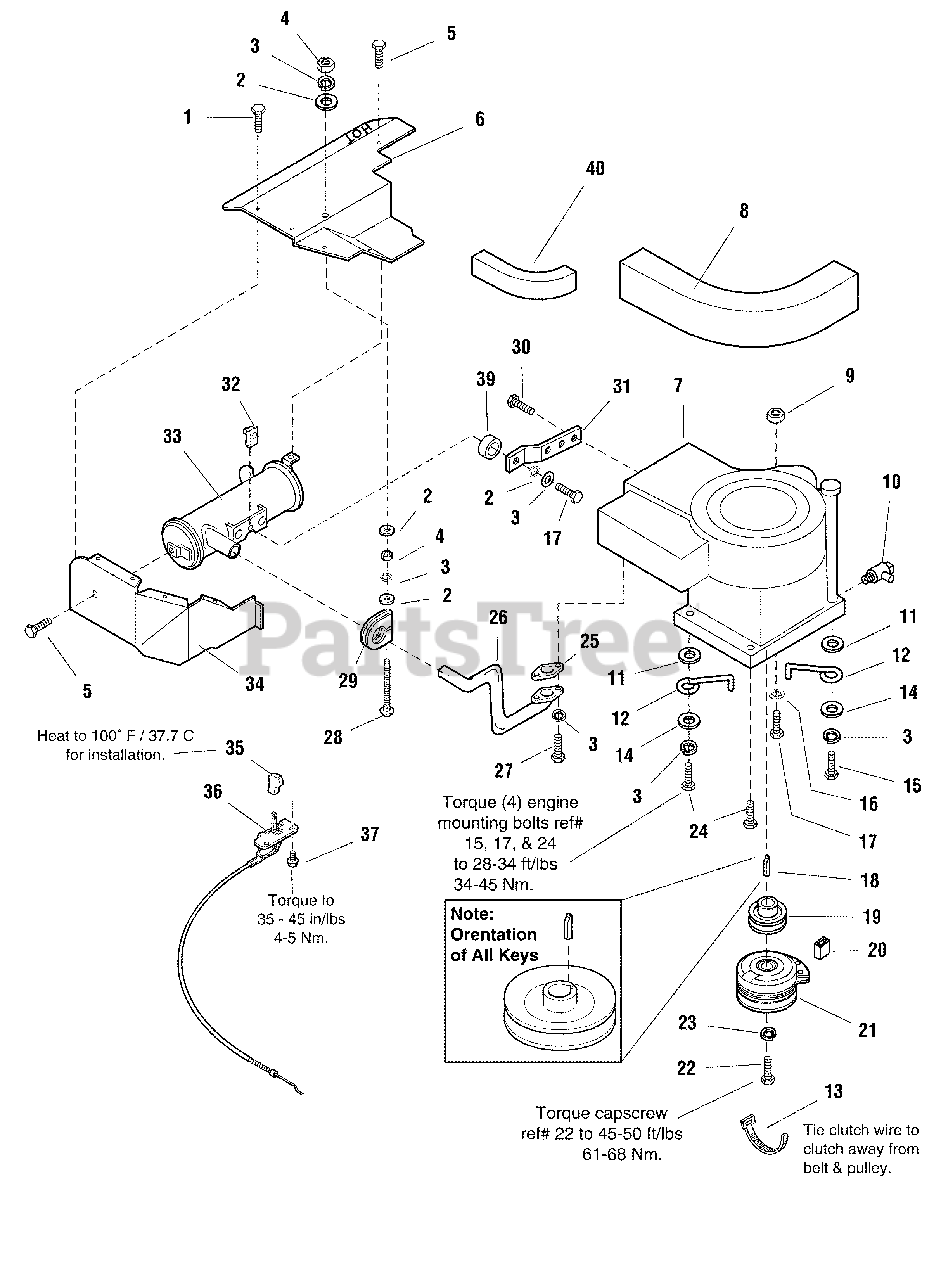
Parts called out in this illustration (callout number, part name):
1	CAPSCREW, Self-Tapping, #10-16 x 1/2
2	WASHER, 5/16
3	LOCKWASHER, 5/16
4	NUT, Hex, 5/16-18
5	CAPSCREW, Hex Head, Taptite, 5/16-18 x 1/2
6	DUCT, R.H., Top
8	SEAL, Air Inlet
9	NUT, Flange, Whizlock, 5/16-18
10	VALVE, Shut-Off
11	WASHER, Plain
13	TIE, Self Locking
14	WASHER, 3/8
15	CAPSCREW, Taptite, 3/8-16 x 2
16	PUSH NUT, 5/16-18
17	CAPSCREW, Hex, Whizlock, Flange, 5/16-18 x 1-1/2
18	KEY, Hi-Pro
19	PULLEY, Engine
20	SLEEVE, Clutch Anchor
21	CLUTCH, Electric, Kit
22	CAPSCREW, Hex Head, 7/16-20 x 2-1/2
23	LOCKWASHER, 7/16
24	CAPSCREW, Taptite, 3/8-16 x 1-1/2
25	GASKET, Muffler
26	PIPE, Exhaust
27	CAPSCREW, Socket Head, 5/16-18 x 3/4
28	CARRIAGE BOLT, 5/16-18 x 3-1/4
29	CLAMP, Muffler
30	CAPSCREW, Hex Head, 1/4-20 x 7/8
31	SUPPORT, Muffler
32	SPEED NUT, 5/16-18
33	MUFFLER ASSEMBLY
35	KNOB, Throttle
36	THROTTLE CONTROL ASSEMBLY
37	SCREW, Plastite, 1/4-10 x 1/2
38	STOP, Throttle (Not Pictured, Export Models Only)
40	SEAL, Edging
